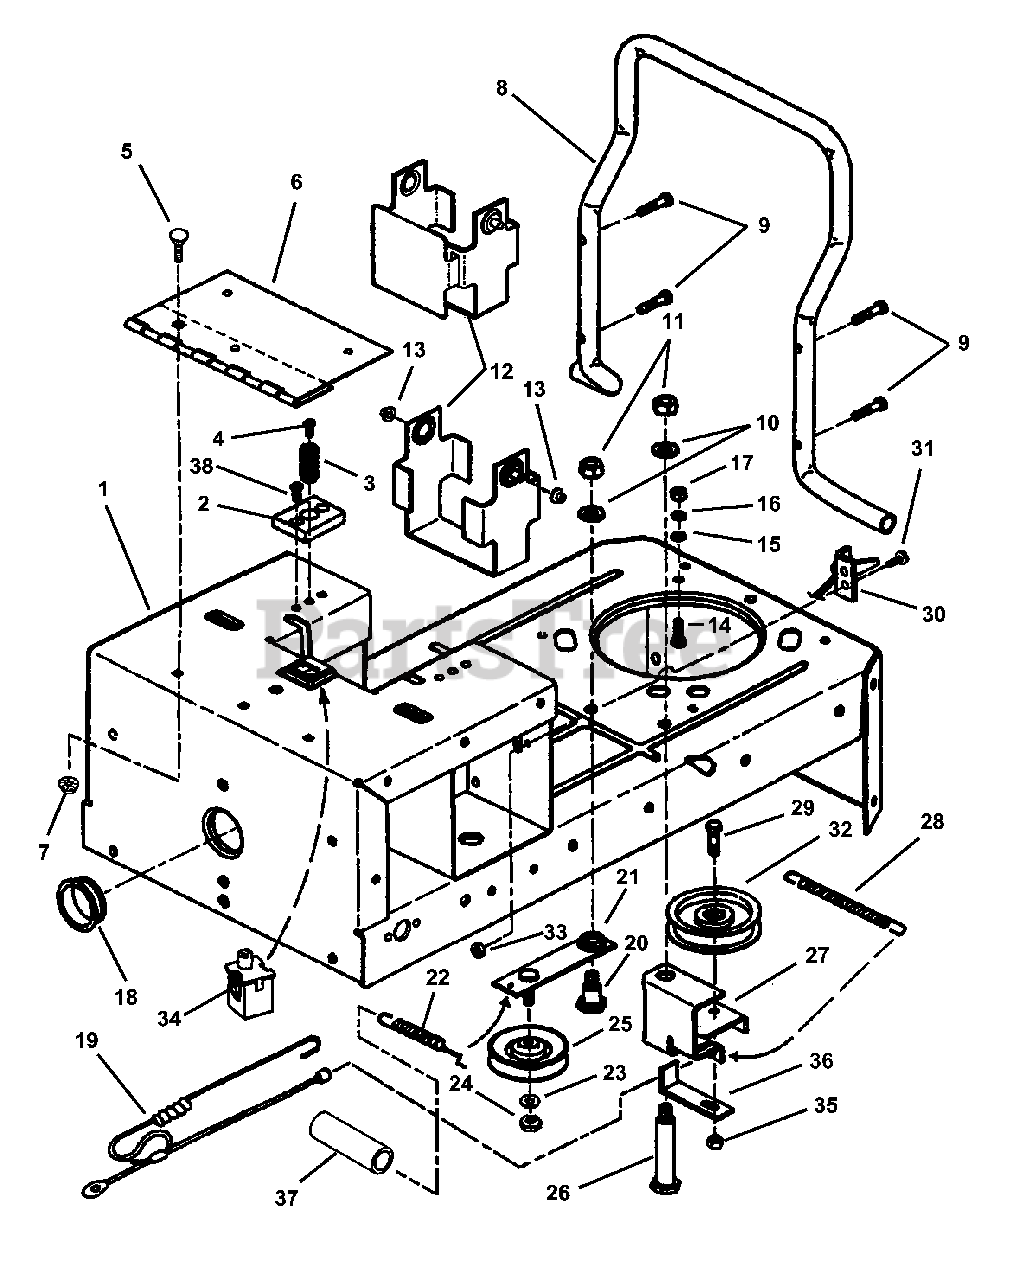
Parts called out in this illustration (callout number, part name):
1	FRAME, Rear
2	CUSHION, Seat Support
3	SPRING, Seat Support
4	SCREW, 1/4-20 x 5/8" Pan Head, Self-Tapping
5	BOLT, 5/16-18 x 1/2" Carriage, Grade 5
6	HINGE, Seat
7	NUT, 5/16-18 Hex Flange Lock, Grade 5
8	BUMPER, Rear
9	SCREW, 5/16-18 x 1-1/2" Hex Washer Head, Self-Tapping
10	WASHER, 1/2" Flat
11	NUT, 1/2-13 Hex, Grade B
12	BRACKET, Battery
13	BUSHING
14	SCREW, 5/16-24 x 1" Hex Head Cap
15	RETAINER, 5/16 Bolt
16	WASHER, 5/16 Split Lock
17	NUT, 5/16-24 Hex, Grade 5
18	GROMMET
19	CABLE, Brake/Clutch
20	BOLT, 1/2-13 x 5/8" Thread, .75 x .788 Shoulder
21	WELDMENT, Primary Idler Arm
22	SPRING, Clutch/Brake (5" long)
23	WASHER, 3/8" Flat
24	NUT, 3/8-16 Hex Center Lock, Grade 5
25	PULLEY, Idler 3.30 Dia.
26	BOLT, 1/2-13 x 5/8" Thread, .75 x 3.23 Shoulder
27	BRACKET, Hydraulic Idler
28	SPRING, Drive Idler (3/4" x 10" long)
29	SCREW, 5/16-18 x 1" Hex Head Cap, Grade 5
30	CABLE, Hydro Release Valve
31	SCREW, #10-32 x 5/8" Hex Washer Head, Machine
32	IDLER, 4.12 Flat
33	NUT, #10-32 Hex Nyloc
34	SWITCH, Seat (NC/NO)
35	NUT, 5/16-18 Hex Center Lock
36	GUIDE, Belt
37	COVER, Spring
38	FASTENER, Ratchet
